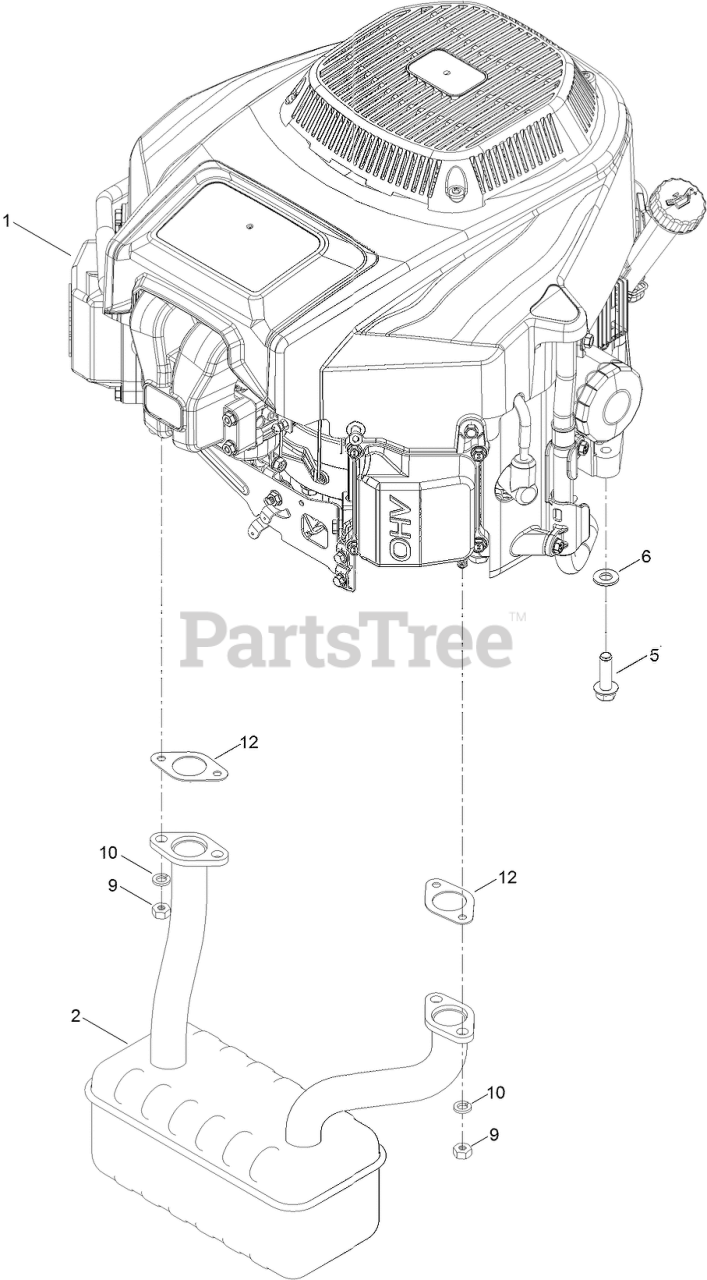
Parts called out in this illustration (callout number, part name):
1	ENGINE-2P77F
2	MUFFLER
5	SCREW-HWH, THD ROLL
6	WASHER-FLAT
9	NUT-HH
10	WASHER-LOCK, SPLIT
12	GASKET-EXHAUST
